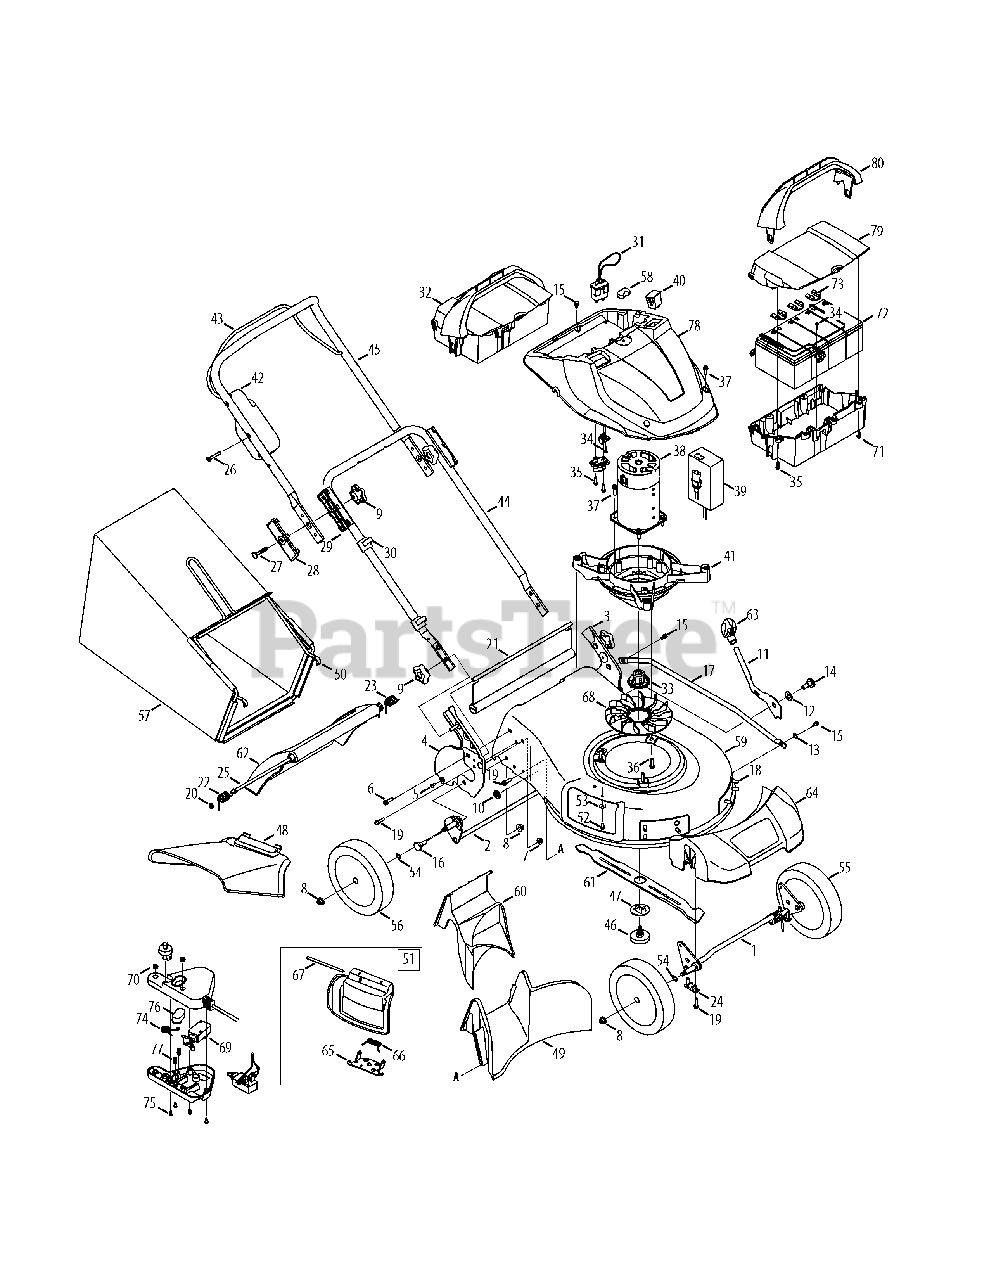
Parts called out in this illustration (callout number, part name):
1	Front Bracket Assembly
2	Rear Bracket Assembly
3	LH Bracket Assembly
4	RH Bracket Assembly
5	Screw, #10-16 x .500
6	Hex Screw, 5/16-18 x .625
7	Flangelock Nut, 5/16-18
8	Flangelock Nut, 3/16-18
10	Spacer, .515 X 1.00 X .310 LG
11	Height Lever
12	Bell Washer, .510 x 1.14 x .040
13	Wave Washer, .385 ID X .598 OD
14	Shoulder Screw, .50 x .66
15	Shoulder Screw, 1/4-20:0.50
16	Shoulder Screw, .500 x .434
17	Height Bracket
18	Hi-lo Screw, 5/16-14 x.750
19	Hi-lo Screw, 1/4-15 x1.00
20	Speed Nut
21	Trailshield
22	RH Torsion Spring
23	LH Torsion Spring
26	Flat Screw, 1/4-20 1.75
27	Carrriage Bolt, 5/16-18 2.50
28	Upper Handle Insulator
29	Lower Handle Insulator
30	Cable Guide
32	Replaceable Battery
33	Fan Assembly
34	Screw, 1.59 x .610
35	Hi-lo Screw, #12-16:.75
36	Screw, 5/16-12:0.750
37	Hi-lo Screw, 1/4-15:0.750
39	Battery Charger
40	Battery Level Indicator
41	Motor Bracket
42	Switch Assembly
43	Switch Bail
45	Upper Handle
46	Blade Assembly Bolt
47	Blade Locking Plate
48	Discharge Chute
49	Rear Baffle
50	Grass Bag Frame
51	Mulch Plug
52	Taptite Screw, 1/4-20 x .500
53	Bell Washer, .265 x .75 x .062
54	Wave Washer, .510 x .750 x .017
55	Front Wheel
56	Rear Wheel
58	Locking Knob
60	Mulch Plug
63	Height Adjust Knob
64	Front Axle Cover
65	Chute Deflector Adaptor
66	Torsion Spring, .290 ID x 1.68
67	Hinge Pin, .250
69	Switch Button
70	Hexlock Nut, 1/4-20
71	Screw, #12-16:.50
72	12V Battery
73	Battery Jumper
74	Torsion Spring
75	Screw, 10-9 x .50
76	Bail Lock
77	Compression Spring, .260 x .687
78	Motor Shroud
79	Battery Cover
80	Battery Handle
